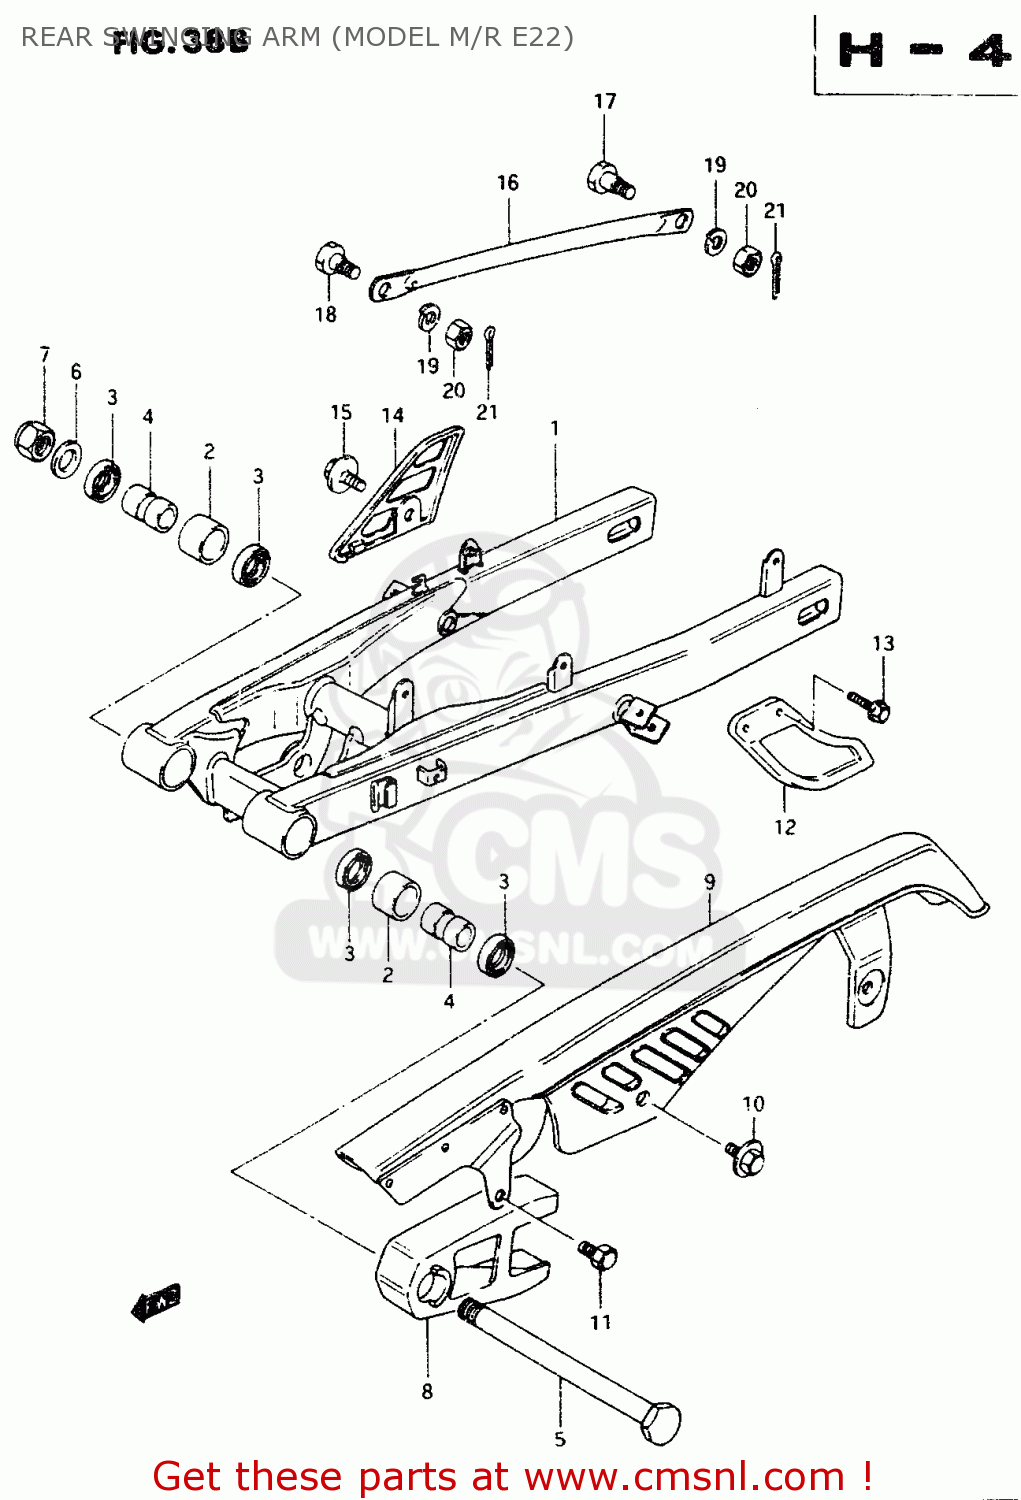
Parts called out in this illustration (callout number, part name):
1	RR.SWINGINGARM
2	BUSHING,RR SWGARM PIVOT
3	OIL SEAL
4	SPACER,RR SWINGING ARM PIVOT
5	SHAFT,RR
6	WASHER
7	NUT 14MM
8	BUFFER,CHAIN TOUCH DEFENCE
9	CASE,CHAIN
10	BOLT(6X10)
11	BOLT
12	GUIDE,CHAIN
13	BOLT
14	GUARD, FOOT (BLACK)
15	BOLT(6X10)
16	TORQUE LINK,RR
17	BOLT(8X26.5)
18	BOLT(8X22)
19	LOCK WASHER
20	NUT
21	PIN 20X20
